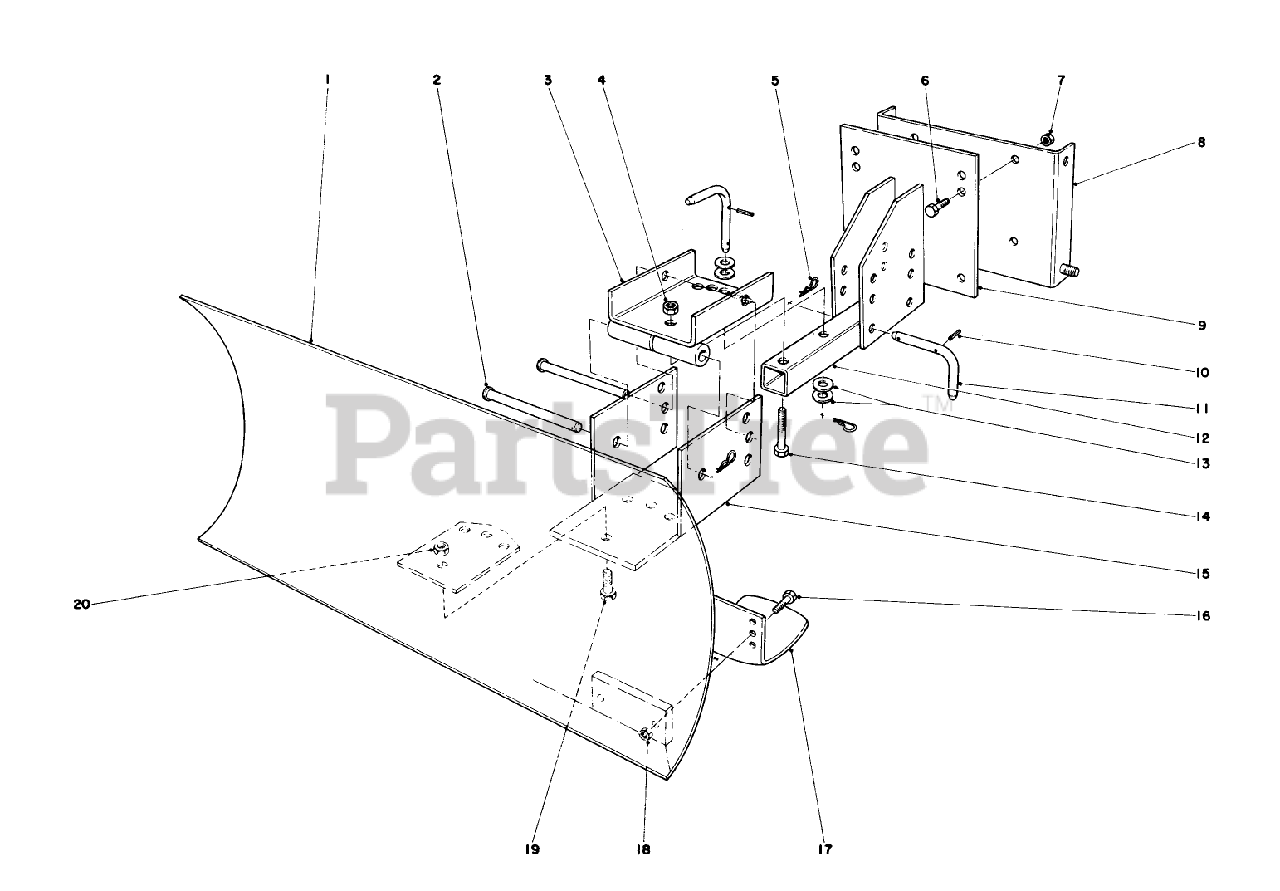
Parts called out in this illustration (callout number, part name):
2	PIN-CLEVIS
5	PIN-HAIR
6	SCREW-HH
7	NUT-LOCK, CONE
10	PIN-SPRING
11	Pivot Pin
13	WASHER-FLAT
14	SCREW-HH
16	SCREW-HH
18	NUT-LOCK, CONE
19	SCREW-HH
